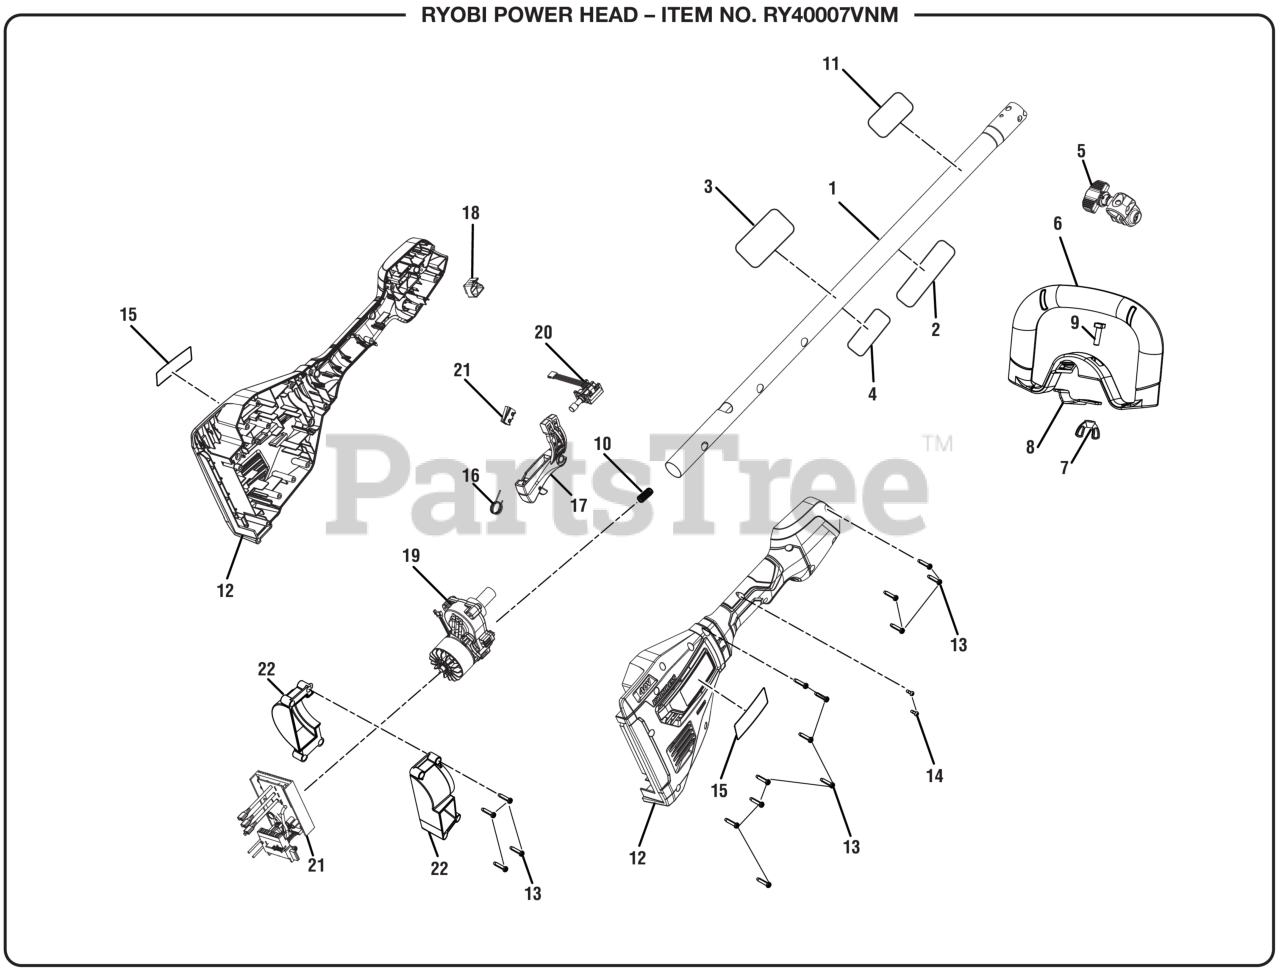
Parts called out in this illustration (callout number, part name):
1	Upper Boom Assembly
2	Warning Label (French/Spanish)
3	Warning Icon Label
4	Data Label
5	Boom Clamp Assembly
6	Front Handle Assembly
7	Wing Nut (1/4-20, Plastic)
8	Front Handle Clamp
9	Bolt (1/4-20 x 1 in., Square Hd.)
10	COMPRESSION SPRING
11	Attachment Label
12	Rear Handle Assembly
13	Screw (M4 x 18 mm, T15 Torx Pan Hd.)
14	Screw (M3 x 8 mm, Pan. Hd.)
15	Logo Label
16	Spring, Torsion, Dia 12.5mm, Music Wire
17	Switch Trigger Assembly w/Lock-Out
18	Hi-Lo Switch Cover
19	Motor and Gear Box Assembly
20	Variable Speed Switch
21	Electric Controller and Switch Assembly
22	Motor Volute Assembly
